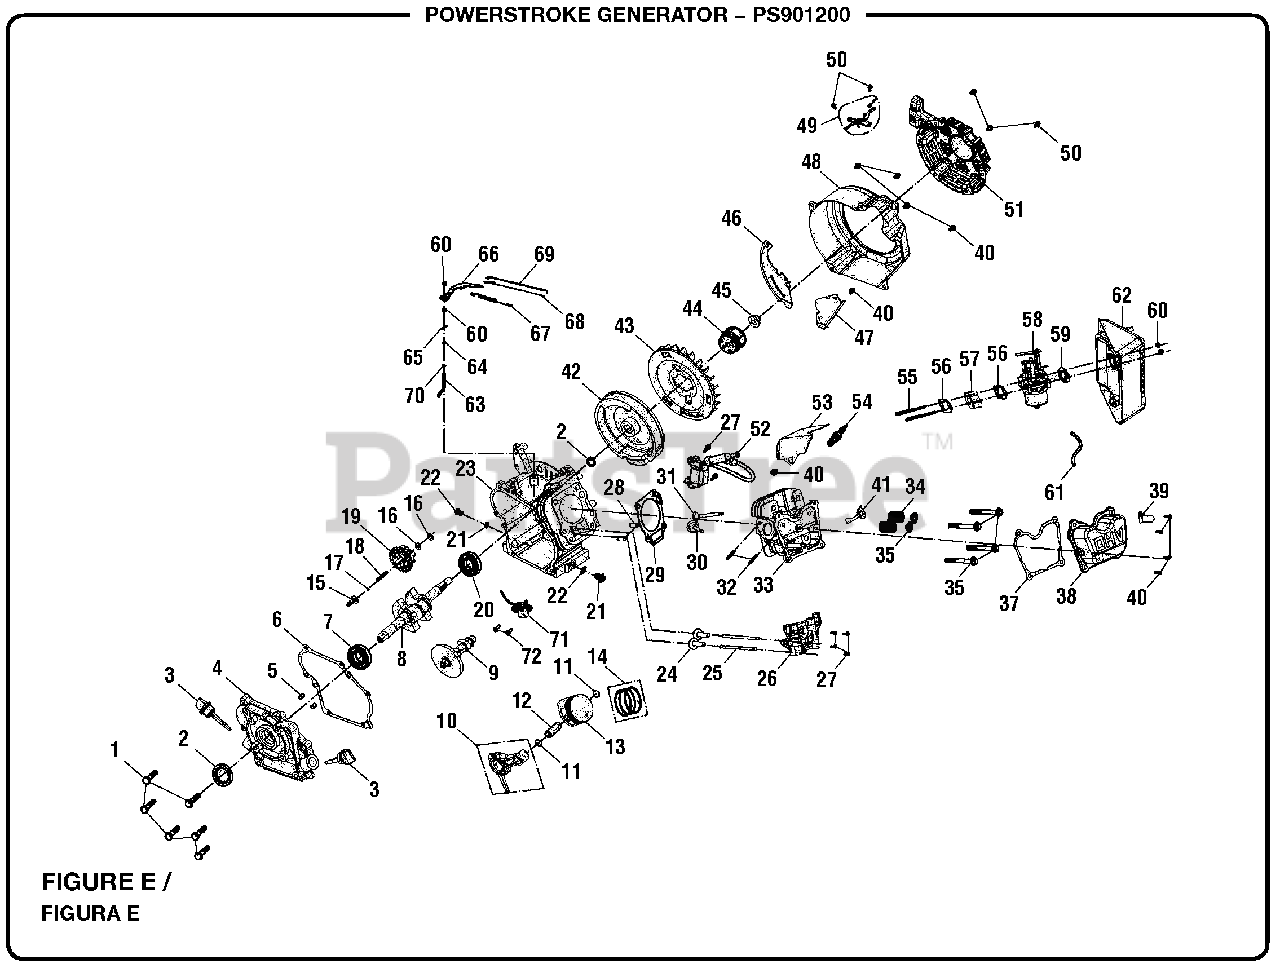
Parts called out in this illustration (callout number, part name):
1	Bolt (M6 x 25 mm, Flange Hd.)
4	Crankcase Cover
5	Cylindrical Pin
6	Crankcase Gasket
7	Ball Bearing (60000-17)
9	Camshaft Assembly
10	Connection Rod Assembly
11	Piston Pin Clip
14	Piston Ring Set
15	Speed Governing Push Dish
16	Speed Swing Rod Washer
18	Regulating Shaft
19	Drive Gear Assembly
20	Ball Bearing (60000-17)
21	Drain Plug Washer
26	Rocker Arm Assembly
27	Bolt (M6 x 18 mm, Flange Hd.)
28	Cylindrical Pin (8 x 16)
29	Cylinder Head Gaskets
30	Exhaust Valve
31	Intake Valve
32	Stud (M8 x 34 mm)
33	Cylinder Head
34	Valve Spring
35	Spring Retainer
36	Bolt (M8 x 50 mm, Flange Hd.)
37	Cylinder Head Cover Gasket
38	Cylinder Head Cover
39	Ignition Coil Assembly Clamp
40	Bolt (M6 × 12 mm, Flange Hd.)
43	Flywheel Fan
44	Starting Flange
45	Flywheel Nut (M12)
46	Retral Baffle Plate
47	Anterior Baffle Plate
49	Governor Assembly
50	Bolt (M6 x 8 mm, Flange Hd.)
51	Recoil Starter
52	Ignition Coil
53	Upper Fan Hood Assembly
55	Stud (M6 x 91 mm)
56	Carburetor Gasket
57	Carburator Block
59	Air Cleaner Gasket
60	Flange Nut (M6)
62	Air Cleaner Assembly
63	Regulating Sway Bar
64	Regulating Sway Bar Gasket
66	Regulating Arm
67	Governor Spring
68	Reset Spring
69	Governor Pull Rod
70	Governor Washer
72	Screw (M6 x 16 mm)
